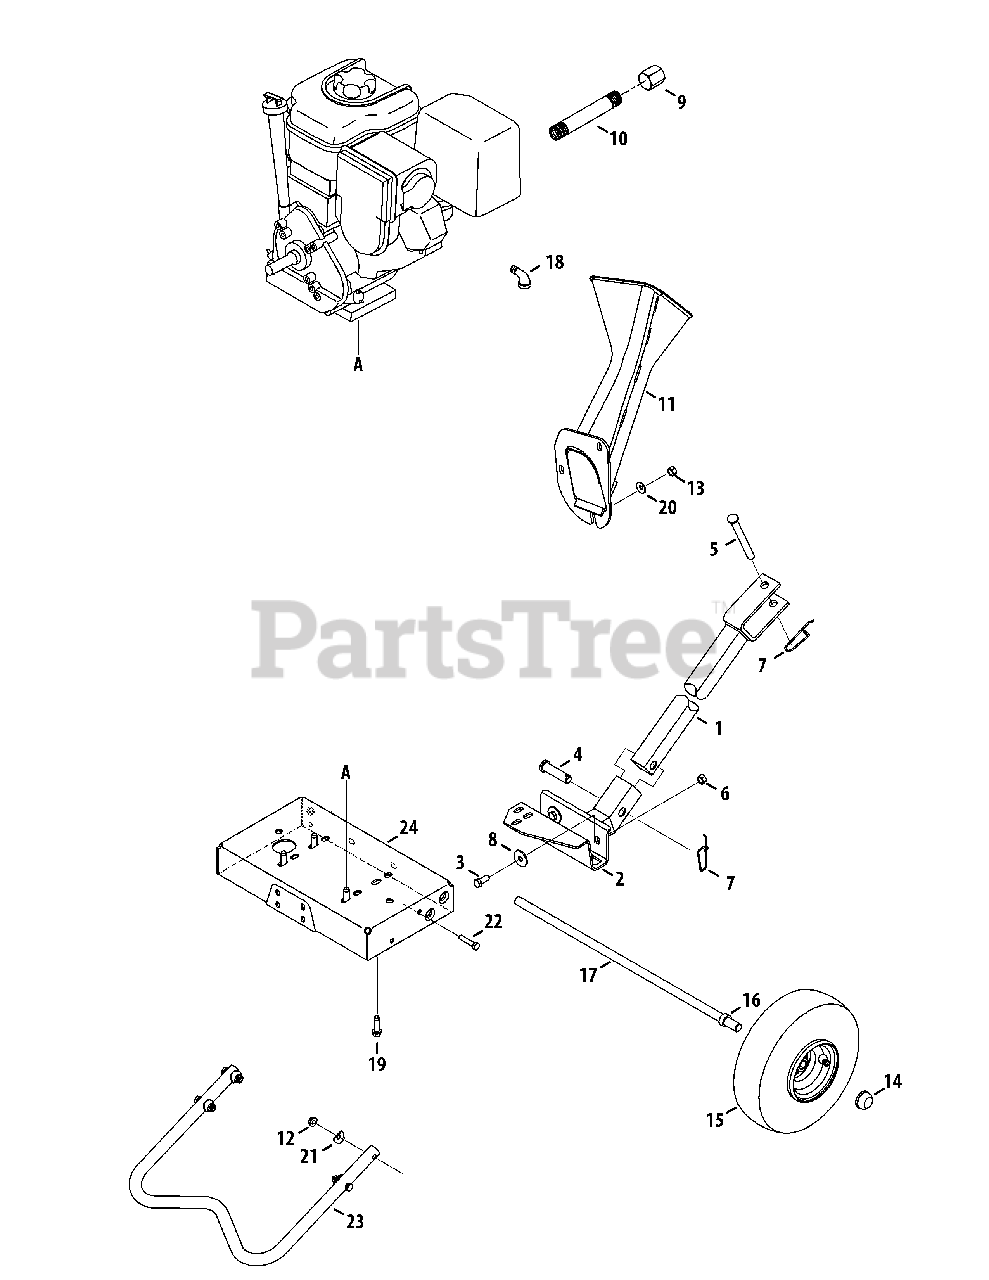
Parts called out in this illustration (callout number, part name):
1	Tongue Hitch Mount
2	Base Hitch Mount
3	Hex Cap Screw, 3/8-16 x.88
4	Clevis Pin,.625 x 2.4
5	Clevis Pin,.50 x 4.62
6	Flange Lock Nut, 3/8-16
7	Spring Pin
8	Flat Washer,.411 x 1.25 x 1.0
9	End Cap, 1/4 NPT
10	Pipe, 1/4 NPT x 3.5 LG
11	Chipper Chute
12	Flange Lock Nut, 5/16-18
13	Hex Nut, 5/16-18
14	Push Cap, 5/8
15	Wheel, 10 x 4 x 4
16	Spacer, .64 x .88 x .38
17	Axle, 22.47"
18	Elbow Fitting
19	Hex Sems Screw, 3/8-16 x 1.25
20	Bell Washer.340 ID x.872 OD
21	Washer,.320 ID x.93 OD
22	Hex Cap Screw, 5/16-18 x 1.50
24	Frame Assembly
